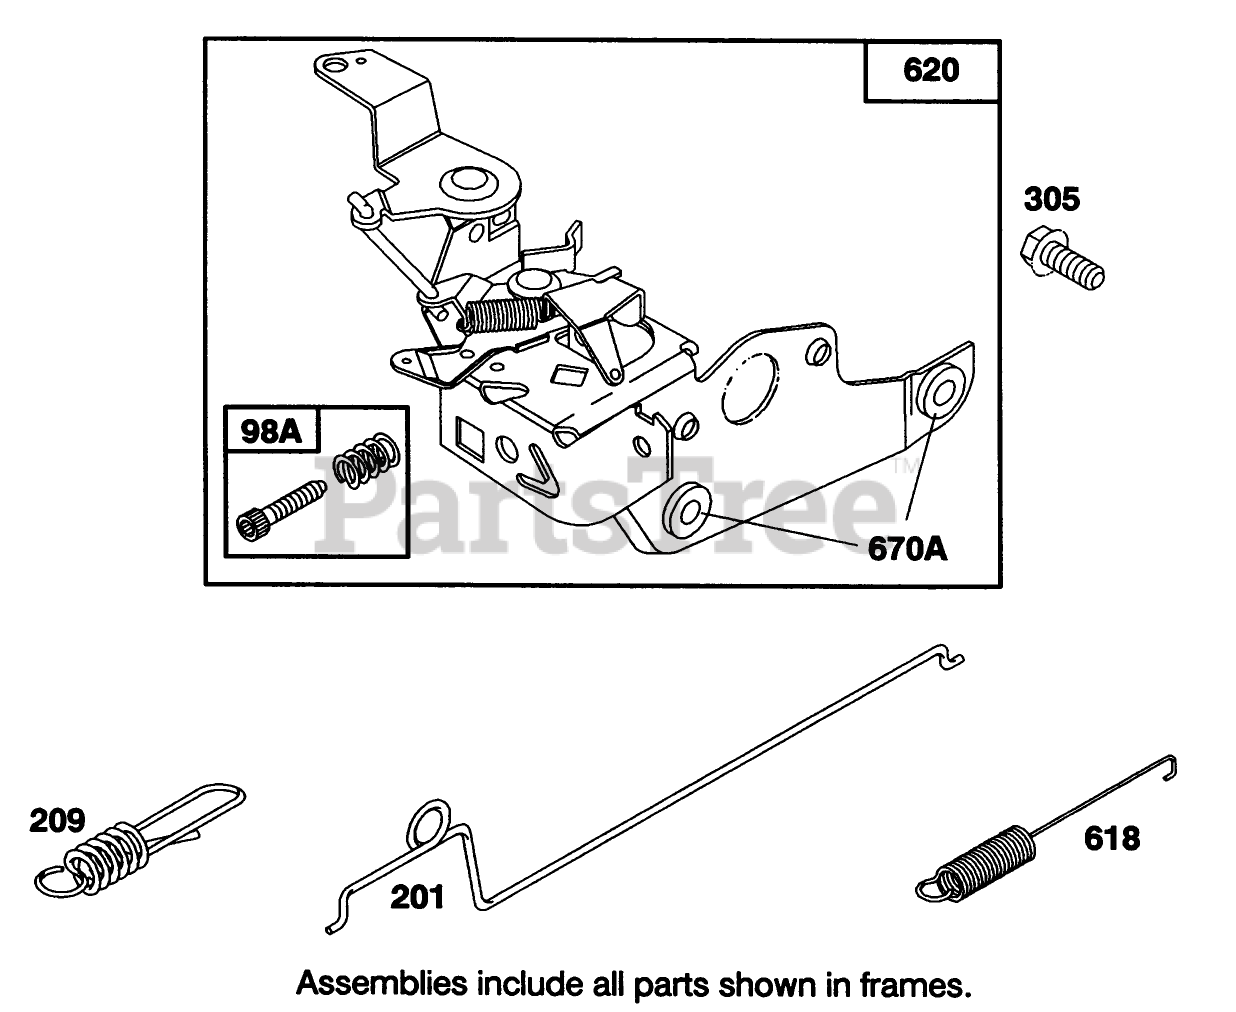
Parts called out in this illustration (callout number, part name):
98A	Screw Assy.
201	Link-Govemor
209	Spring-Govemor
305	Screw-Sem
618	Spring-Choke
620	Bracket Assembly
670A	Spacer
